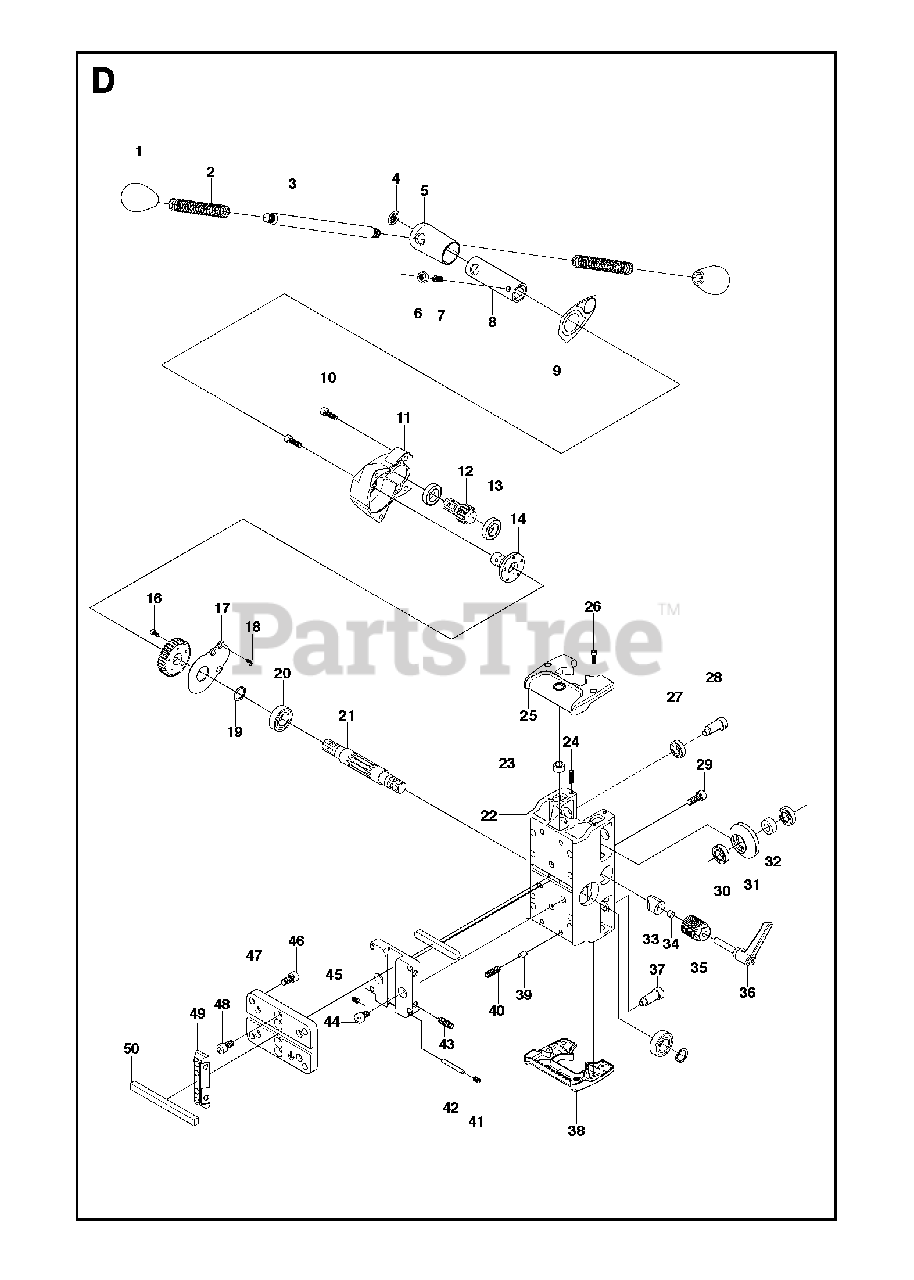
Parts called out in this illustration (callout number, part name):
10	SCREW IHSCM
43	SCREW IHSETM
46	QUICK ATTACH DOVE TAIL RECEIVER
